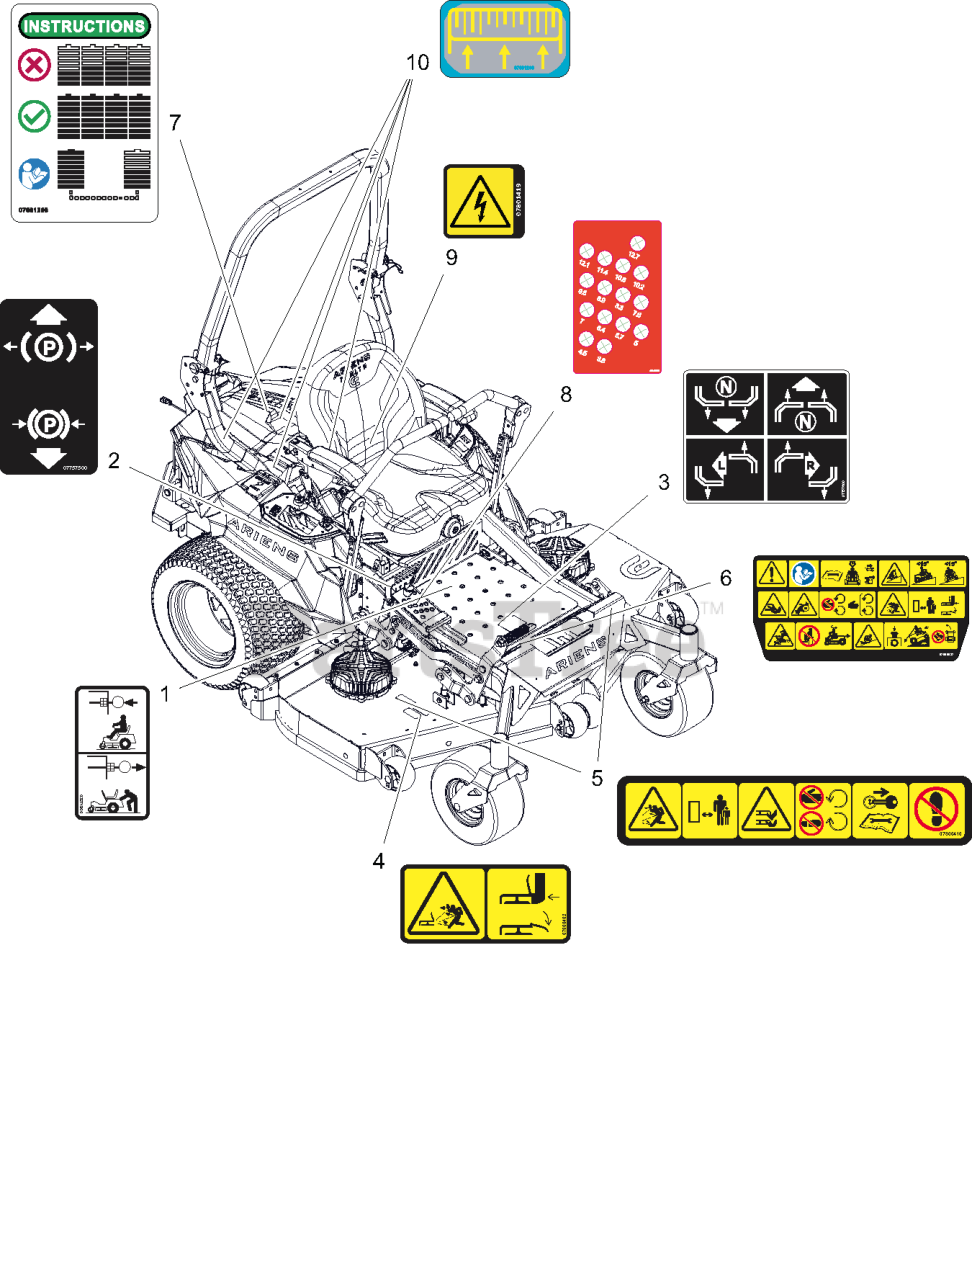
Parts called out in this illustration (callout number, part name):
1	DECAL, DANGER
2	DECAL, TRANSMISSION DISCONNECT
3	DECAL, PARKING BRAKE LEVER
4	DECAL, INSTRUCTIONAL-STEERING
5	DECAL, SAFETY - DECK GUARDING
6	DECAL, DECK SAFETY
7	DECAL, MAIN SAFETY
8	DECAL, BATTERY BALANCE
9	DECAL, APEX HOC METRIC
10	DECAL, SAFETY - DANGER
11	DECAL, BATTERY INSTALL DIRECTION
